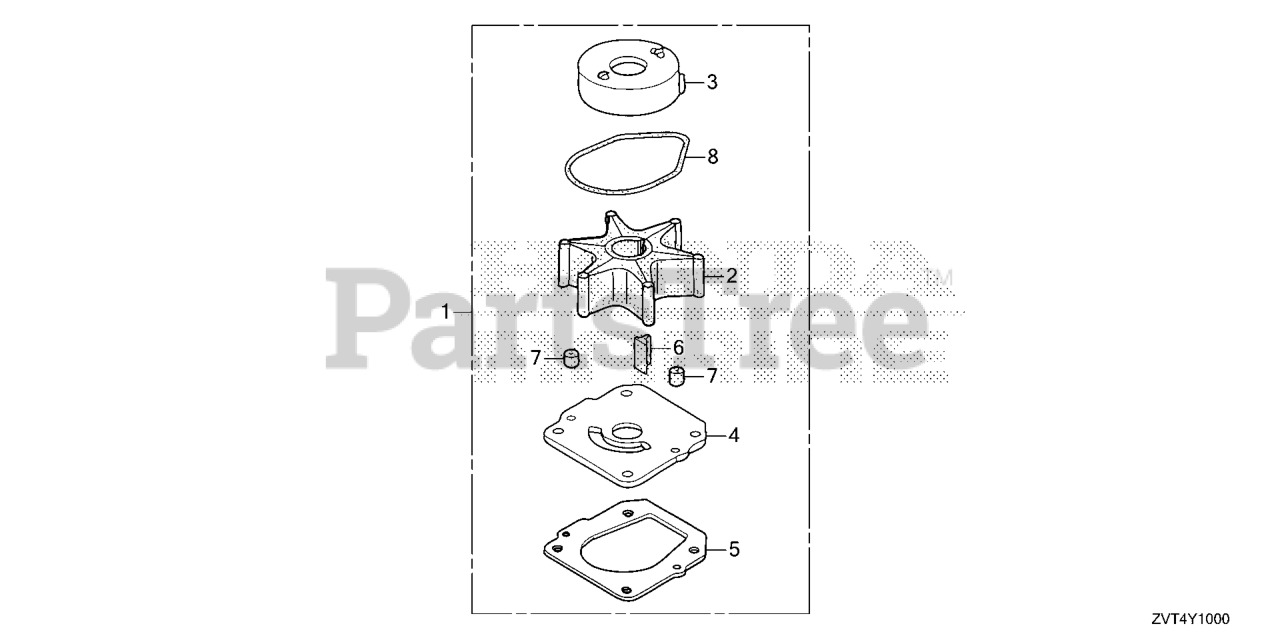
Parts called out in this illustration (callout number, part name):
1	PUMP KIT, IMPELLER
2	IMPELLER, PUMP
3	LINER, PUMP
4	COVER, IMPELLER
5	GASKET B, IMPELLER
6	KEY, WOODRUFF
7	PIN, DOWEL (6X10)
8	O-RING, WATER PUMP
